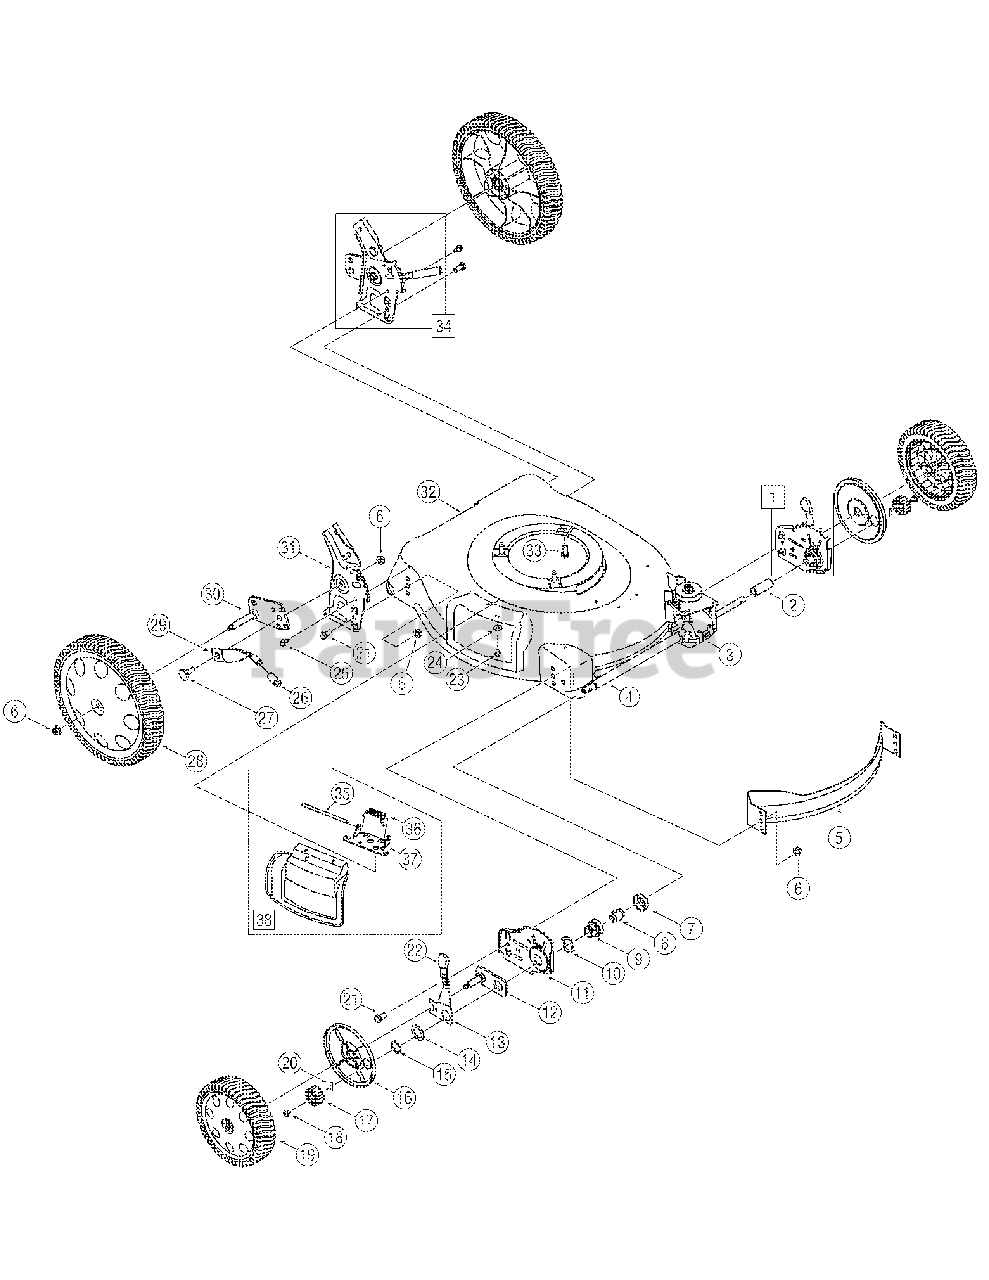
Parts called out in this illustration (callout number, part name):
1	Height Adj. Assembly - LH
1	Height Adj. Assembly - RH
2	Sleeve Spacer 1.8" Long
3	Transmission
4	Sleeve Spacer 9.10" Long
5	Front Baffle
6	Flange Lock Nut, 3/8-16
7	Bearing Retainer
8	Sleeve Bearing
9	Bearing Support
10	Wave Washer
11	Front Height Adj. Plate - RH
11	Front Height Adj. Plate - LH
12	Pivot Plate Assembly
13	Front Lever - RH
13	Front Lever - LH
14	Flat Washer
15	Snap Ring
16	Wheel Dust Cap
17	Gear 14T RH FWD RH
17	Gear 14T LH FWD LH
18	Screw 1/4-20 x .390
19	Front Wheel 8 x 2.125
20	Dowel Pin
21	Hex Screw, 3/8-16 x .75
22	Adjustment Knob
23	TT Screw 1/4-20 x .5
24	Bell Washer
25	TT Screw 1/4-20 x .625
26	Foam Grip
27	Shoulder Screw .500 Dia. X .434
28	Rear Wheel, 12 x 2.125
29	Rear Spring Lever
30	Pivot Arm Assembly - RH
30	Pivot Arm Assembly - LH
31	Handle Bracket - RH
31	Handle Bracket - LH
34	Handle Bracket Assembly - LH
34	Handle Bracket Assembly - RH
35	Hinge Pin
36	Torsion Spring
37	Chute Deflector Adapter
38	Hinged Mulch Plug Assembly
